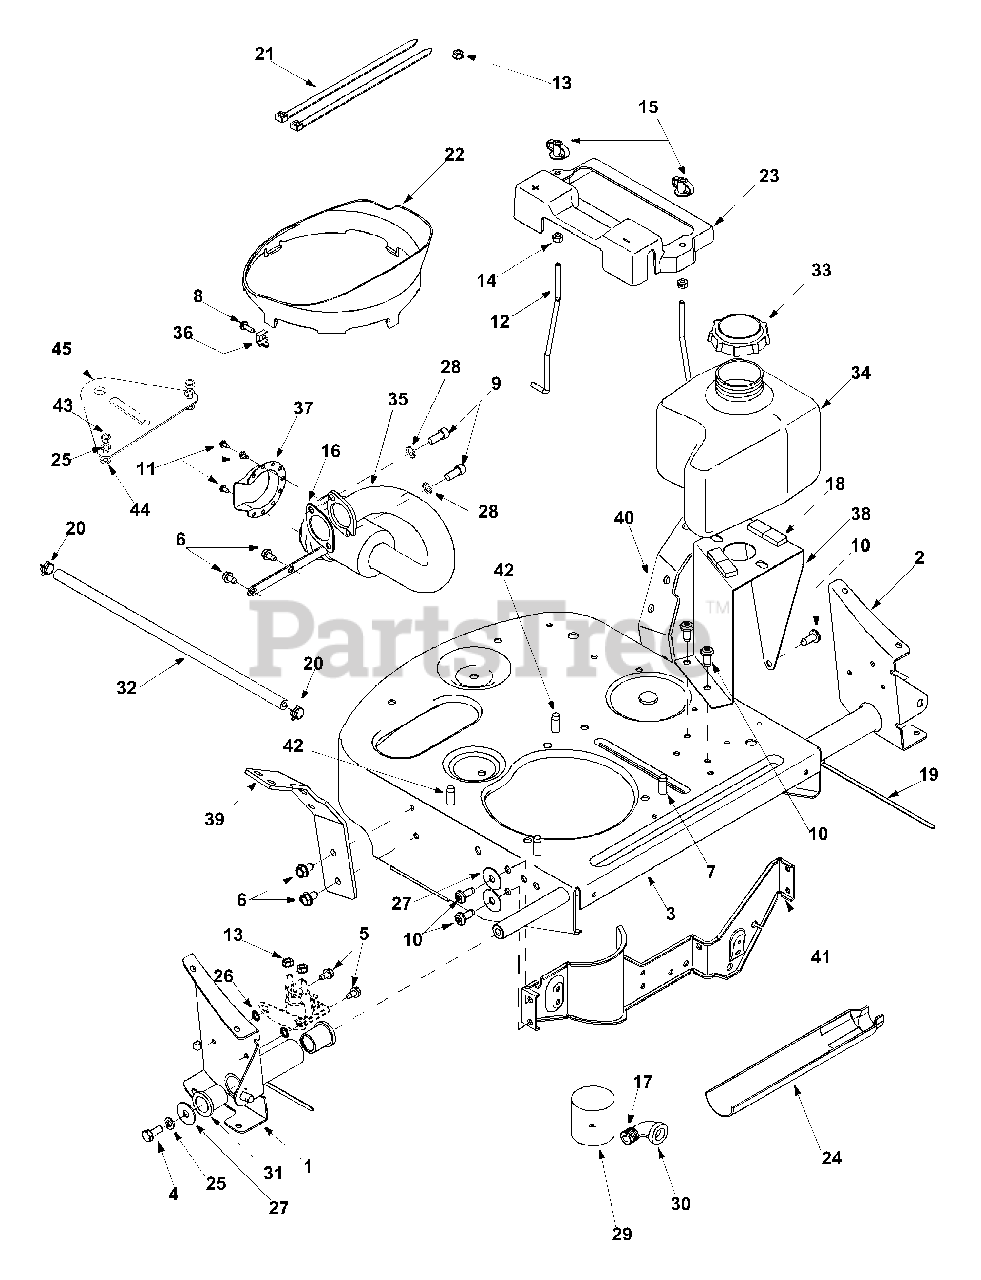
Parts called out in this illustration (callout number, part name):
4	Hex Bolt 5/16-24 x 0.75"
5	TT Screw 1/4-20 x 0.5"
6	TT Screw 5/16-18 x 0.625"
7	TT Sems Screw 3/8-16 x 1.0"
8	T Screw #10-32 x 0.625"
9	Soc. Hd. Screw 5/16-18 x 0.75"
10	TT Screw 5/16-18 x 0.75"
11	AB Screw 8-18 x 0.375"
12	Battery Hold -Down Rod
14	Hex Lock Nut 1/4-20
15	Wing Nut
16	Exhaust Gasket
17	Sealant: Loctite (TM) (not serviceable)
18	Foam Tape: 0.625 x 0.25 thk.
21	Cable Tie
22	Plen
23	Battery Cover
24	Oil drain Sleve
25	Lock Washer 5/16
26	External Lock Washer
27	Flat Washer
28	Lock Washer 1/4
29	SAE 30W Oil (not serviceable)
30	Elbow Feeting
31	Flange Bearing
32	Fuel Line Hose
33	Fuel Cap
34	Fuel Tank
35	Muffler
36	Clamp Casing: Throttle
37	Muffler Deflector
42	Hex Screw 5/16-18 x 0.75"
43	Hex Nut 5/16-18
